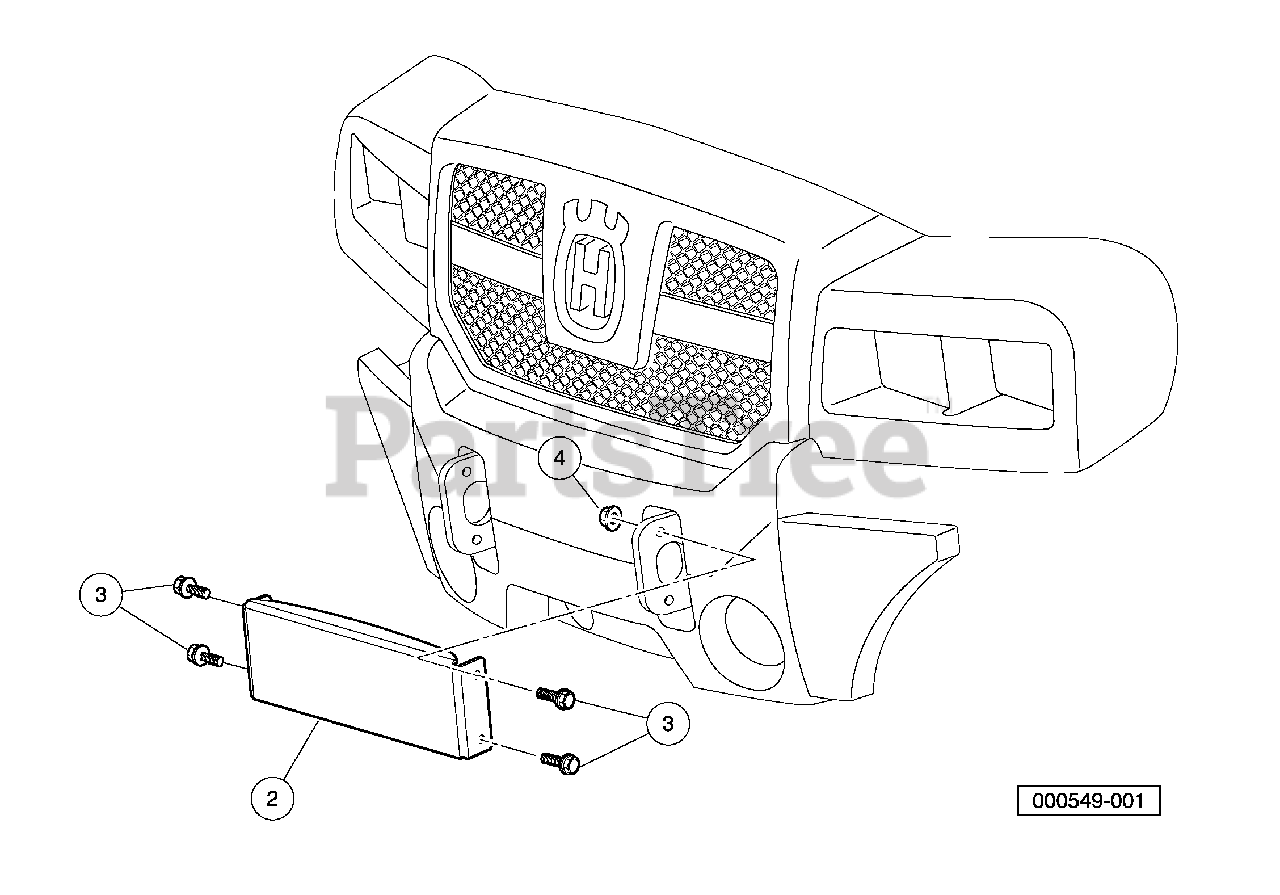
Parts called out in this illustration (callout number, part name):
1	Instl, Bumper Plate, Huv
2	Bumper Plate, Huv
3	Screw, M10 X 1.25 X 30 Hex Blk
4	Nut, Flg, M10 X 1.25 Hex Blk
